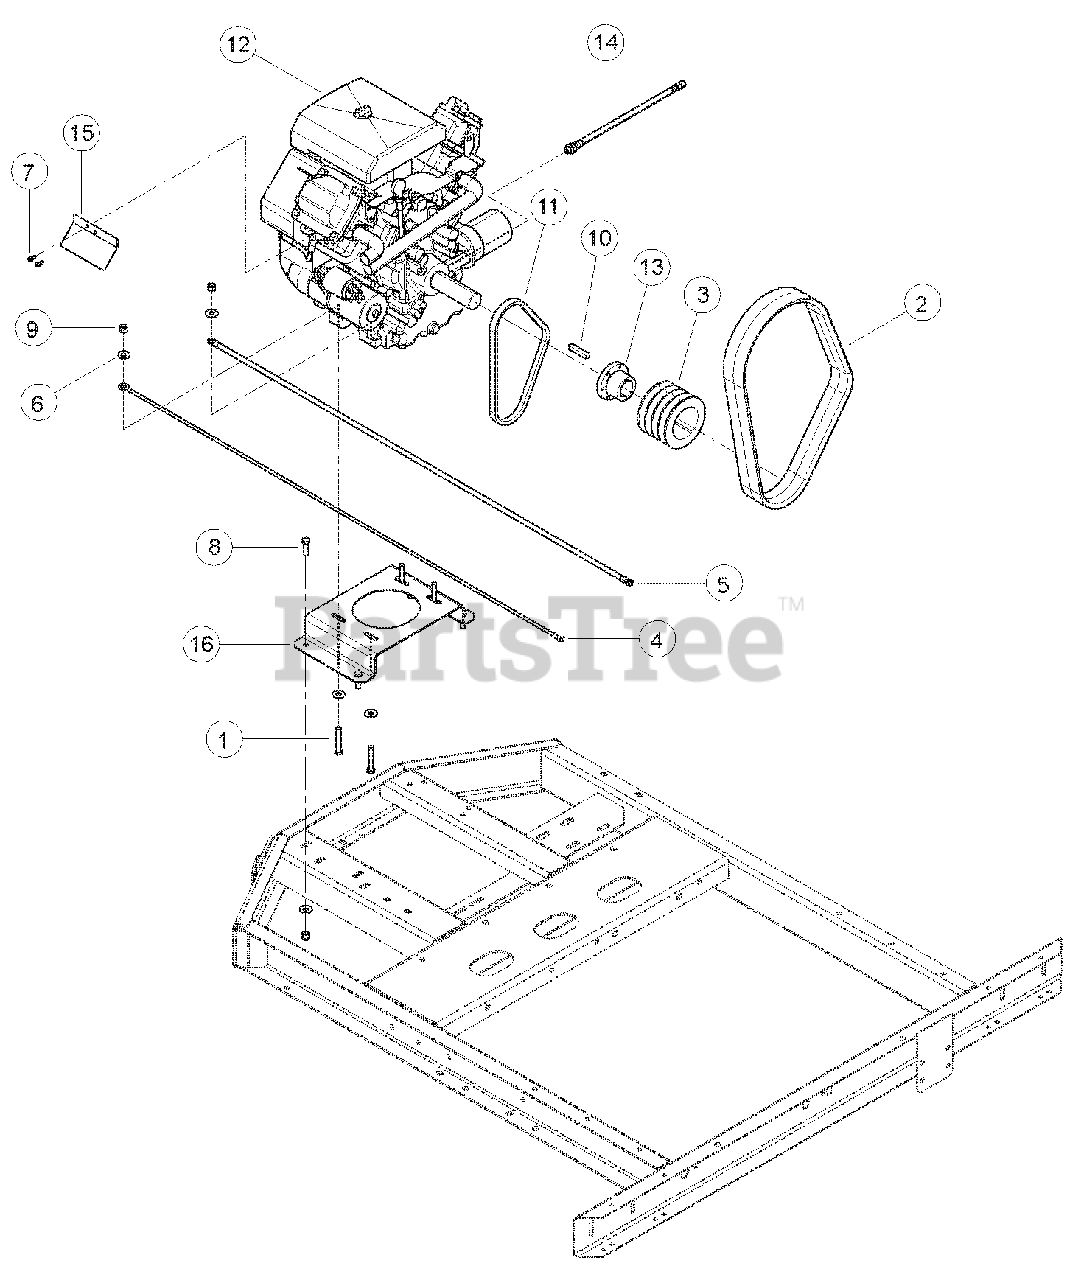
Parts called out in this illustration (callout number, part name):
1	BOLT, 3/8 NC X 2-1/4 HEX HD GR5 ZP
2	BELT, 3RB 48
3	SHEAVE, 4B 4.2 SD
4	CABLE, 50 IN. NEGATIVE (R/R)
5	CABLE, 48 IN. POSITIVE BATTERY
6	WASHER, 3/8 FLAT ZP
7	SCREW, #10 X 1/2 HWH TEK ZP
8	BOLT, 3/8 NC X 1-1/4 HEX HD
9	NUT, 3/8 NYLOCK ZP
10	KEY, 3/8 X 2 SQUARE
11	BELT, 29 IN. C/S
12	ENGINE, KOHLER CH730 (FOR SERVICE SEE OWNER'S MANUAL OR YOUR NEAREST THORIZED KOHLER INDUSTRIAL ENGINE DEALER)
13	BUSHING, 1-7/16 SD
14	HOSE ASSY', CRANKCASE DRAIN
15	GUARD, MUFFLER KOHLER
16	BASE, KOHLER ENGINE
